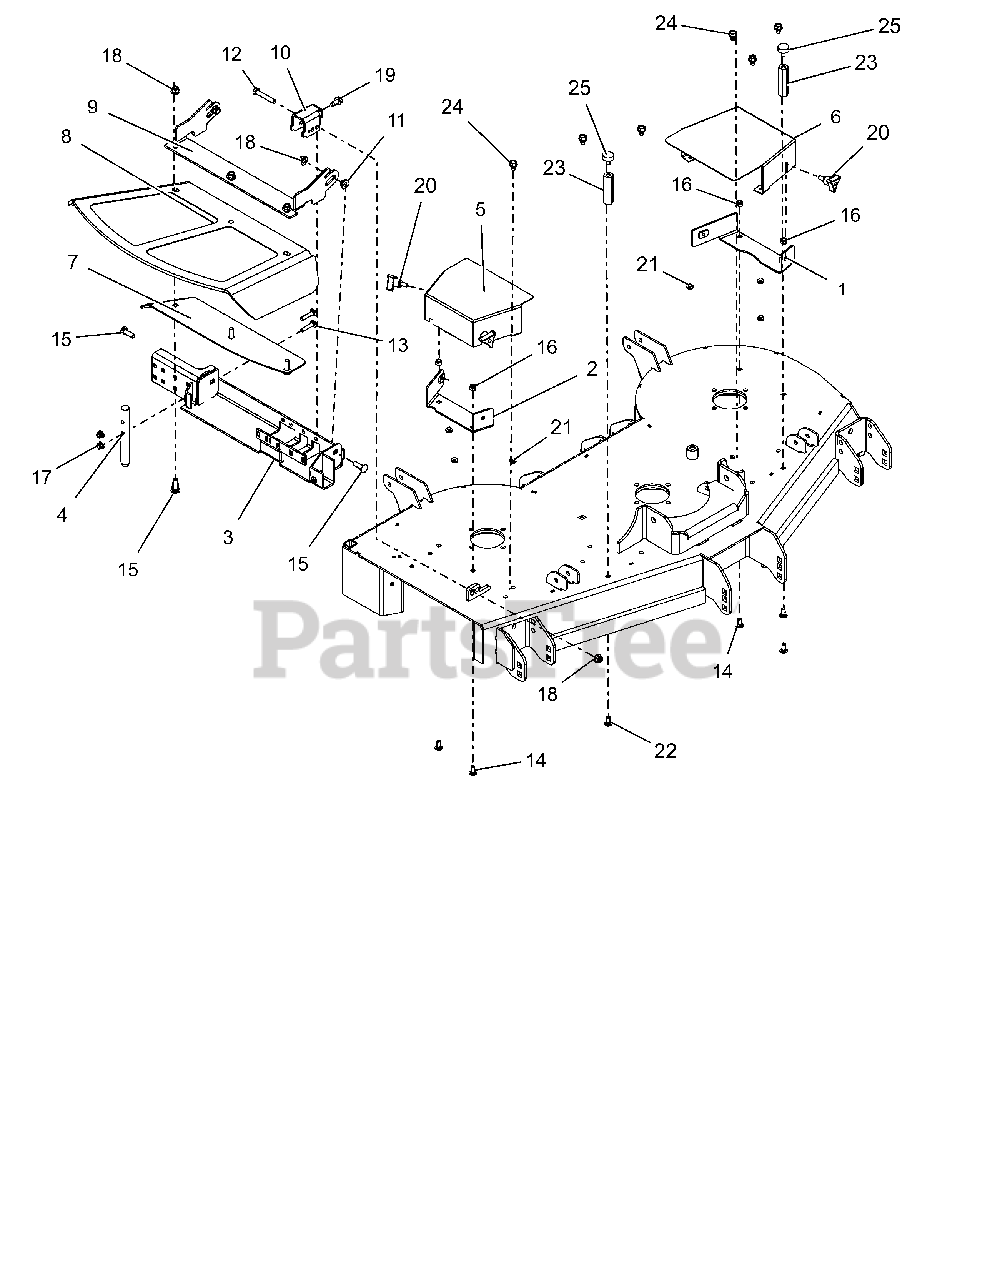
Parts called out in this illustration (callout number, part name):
1	BRKT, LH BELT GUARD MOUNTING
2	BRKT, RH BELT GUARD MOUNTING
3	WLDMT, GRASS CATCHER
4	PIN, DISCHARGE CHUTE X-DRILLED
5	GUARD, RH DECK BELT
6	GUARD, LH DECK BELT
7	48-60 DISCH CHUTE CLMP PLT-BLK
8	CHUTE,48-60" FRMD RUBBER DISCH
9	BRKT, 48-60" CHUTE MTG
10	BRKT, DISCH. CHUTE MTG
11	BSHG-FLG .385X.500X.875X.406
12	@BLT-HEX .38-16X2.25 GR5 YWZC
13	@BLT-RDHDSQNK .31-18X1.50 G5YZ
14	@BLT-RDHDSQNK .31-18X.75 G5YZ
15	@BLT-RHDSSQNK .38-16X1.25 G5YZ
16	@NUT-LK-NYL .312-18 YWZC
17	@NUT-LK-NYL-FLG .31-18 YWZC
18	@NUT-LK-NYL-FLG .38-16 YWZC
19	@SCR-TAP .38-16X.75 HWH TR YWZ
20	KNOB,WING STUD 5/16-18 X .75
21	BUMPER GROMMET
22	BLT,RDHDSQNK .31-18X.75 LOCTIT
23	NUT, COUPLING .31-18 X 3.00
24	@SCR-TAP .38-16X.50 HWH TR YWZ
25	BUMPER, RUBBER
